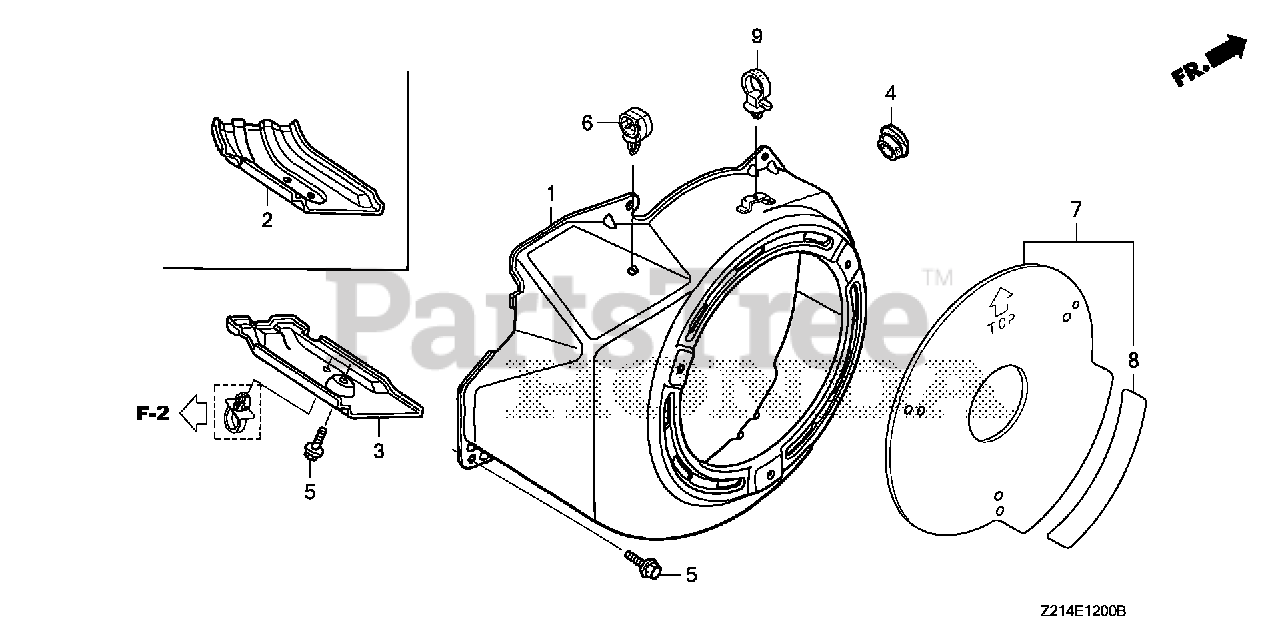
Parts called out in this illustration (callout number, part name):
1	COVER, FAN *NH1* (BLACK)
4	GROMMET, DRAIN HOLE
5	BOLT, FLANGE (6X12) (CT200)
6	CLIP (20MM)
9	BAND, HARNESS (98MM) (NATURAL)
